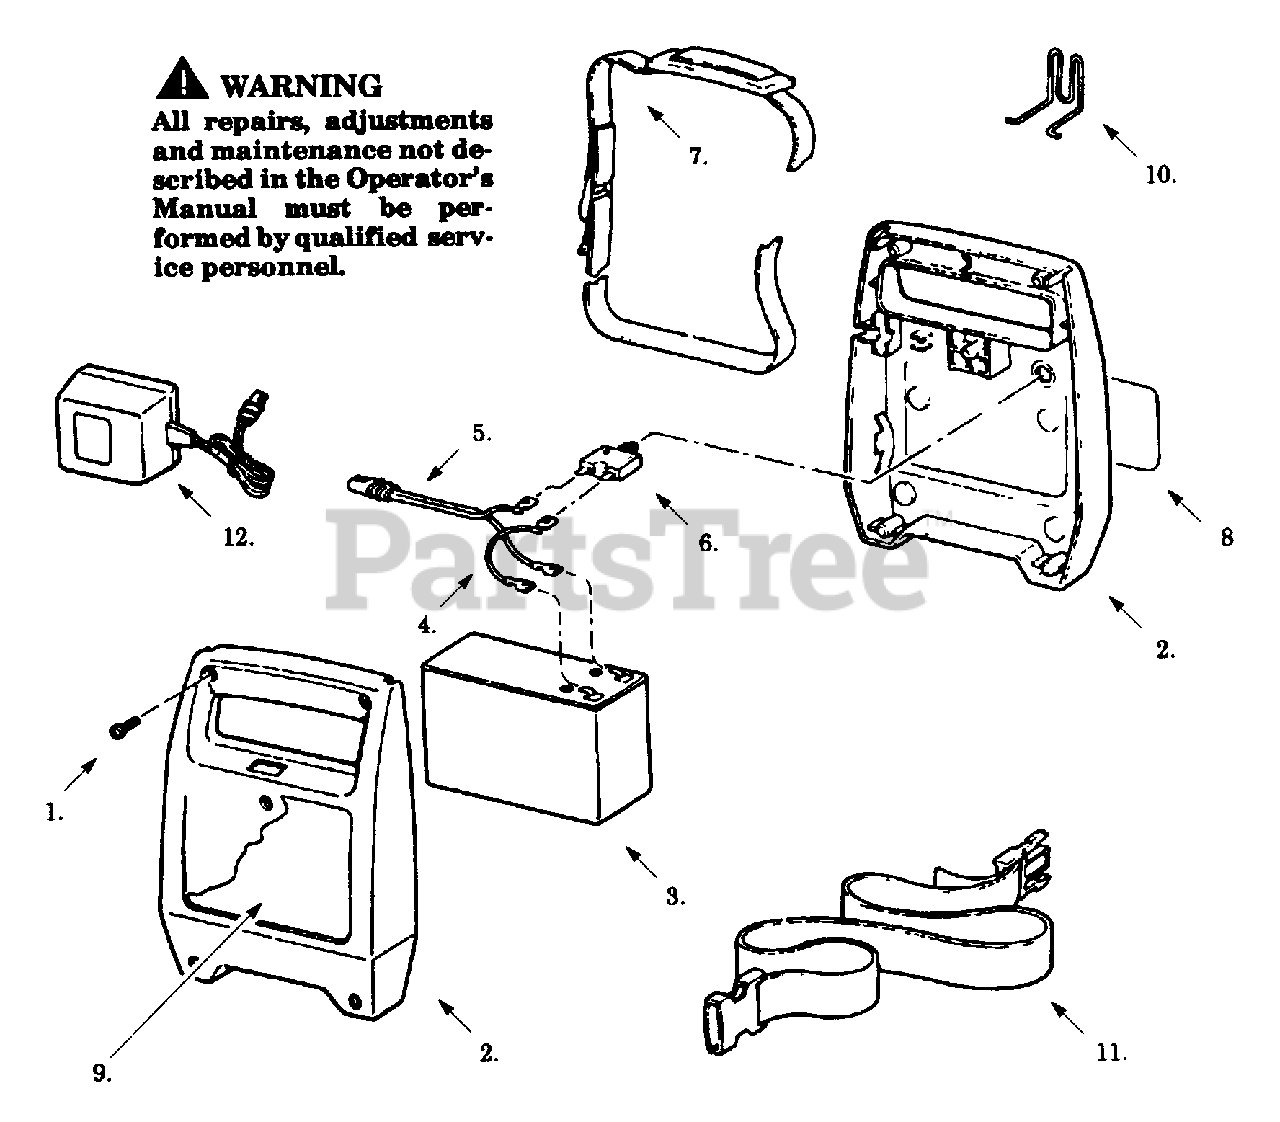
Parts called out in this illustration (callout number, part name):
2	Housing Set
4	Wire Assembly
5	Plug Assembly
6	Circuit Breaker
7	Shoulder Strap
10	Belt Hook
11	Waist Belt
12	Battery Charger
